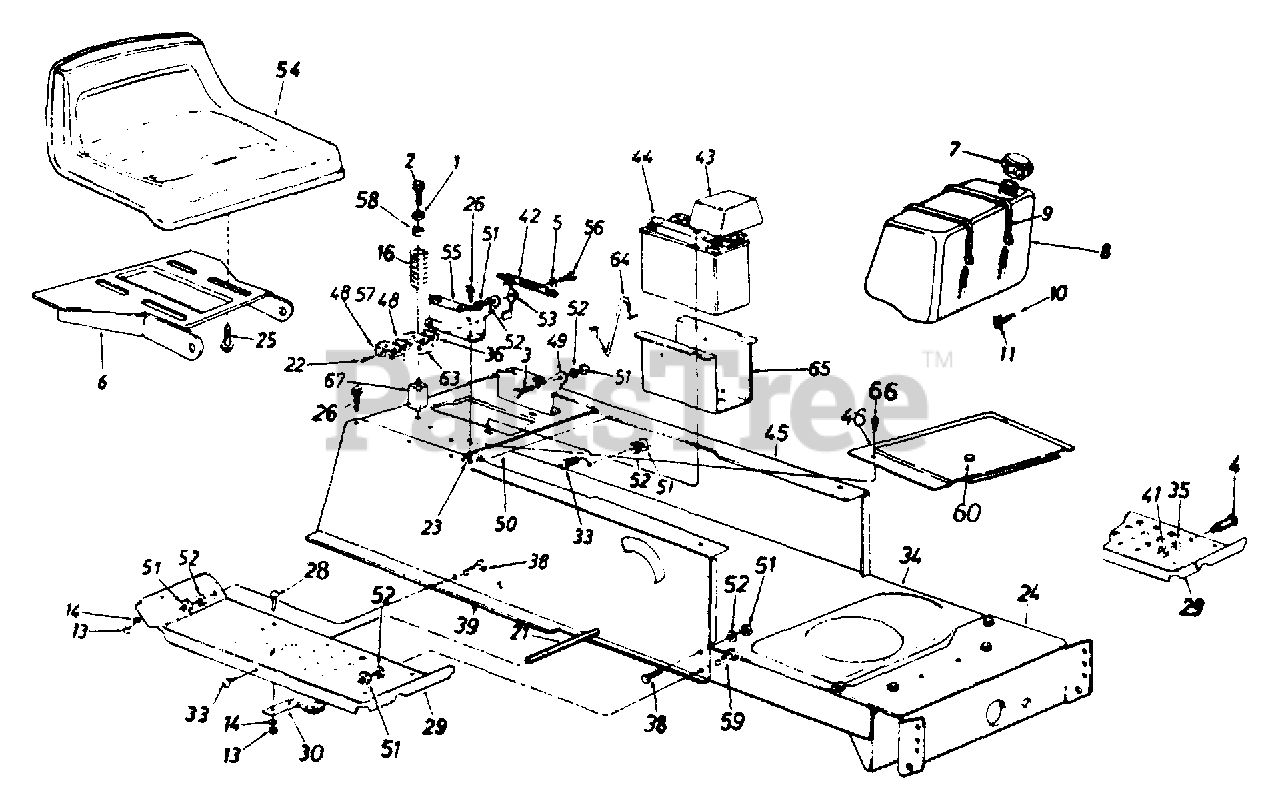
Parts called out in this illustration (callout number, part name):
1	Fl-Wash. .344" I.D. x.875"
2	Hex Wash. Hd. Tap Scr. 5/16-18 x 3.25" Lg.
3	Shld. Bolt .437" Dia. x .162"
4	Shld. Bolt .50" Dia. x .84"
5	Spr-Wash. .445" I.D. x.75
6	Seat Pivot Bracket
7	Fuel Cap
8	Fuel Tank
9	Tie Strap
10	Fuel Line
11	Hose Clamp
13	Hex Nut 1/4-20 Thd.
14	L-Wash. 1/4" I.D.
16	Compression Spring
21	Running Board Rod
22	Hex Wash. Hd. AB-Tap Scr. #8 x .50" Lg.
23	Speed Nut #10Z
24	Front Pivot Brkt.
25	Hex Tap Scr. 3/8-16 x .75"
26	Hex Wash. Hd. AB-Tap Scr. 5/16 x .75" Lg.
28	Carriage Bolt 1/4-20 x .62"
29	Running Board (R.H. & L.H.)
30	Blade Brake Ass'y.
33	Truss Mach. Scr. 5/16-18 x .75" Lg."
34	Lower Frame
35	L-Wash. 3/8" I.D.
36	Insulator Boss Plate
38	Hex Bolt 5/16-18 x .75" Lg.
39	Upper Frame - R.H.
41	Hex Nut 3/8-16 Thd.
42	Extension Spring 5.31" Lg.
43	Battery Cover
44	12-V Battery
45	Upper Frame - L.H.
46	Shift Cover
48	Insulator Plate
52	L-Wash. 5/16" I.D.
53	Seat Lift Brkt.
54	Seat 8-7/8" High
56	Shld. Bolt .437" Dia. x .268"
57	Spring Switch
58	Bushing
59	Hex Wash. TT-Tap Scr. 5/16-18 x 7/8" Lg.
60	Snap Bushing
63	Safety Switch (Seat)
64	Battery Tray Clip
65	Battery Tray
66	Truss Mach. B-Tap Scr. #10 x .5" Lg.
67	Spring Spacer
